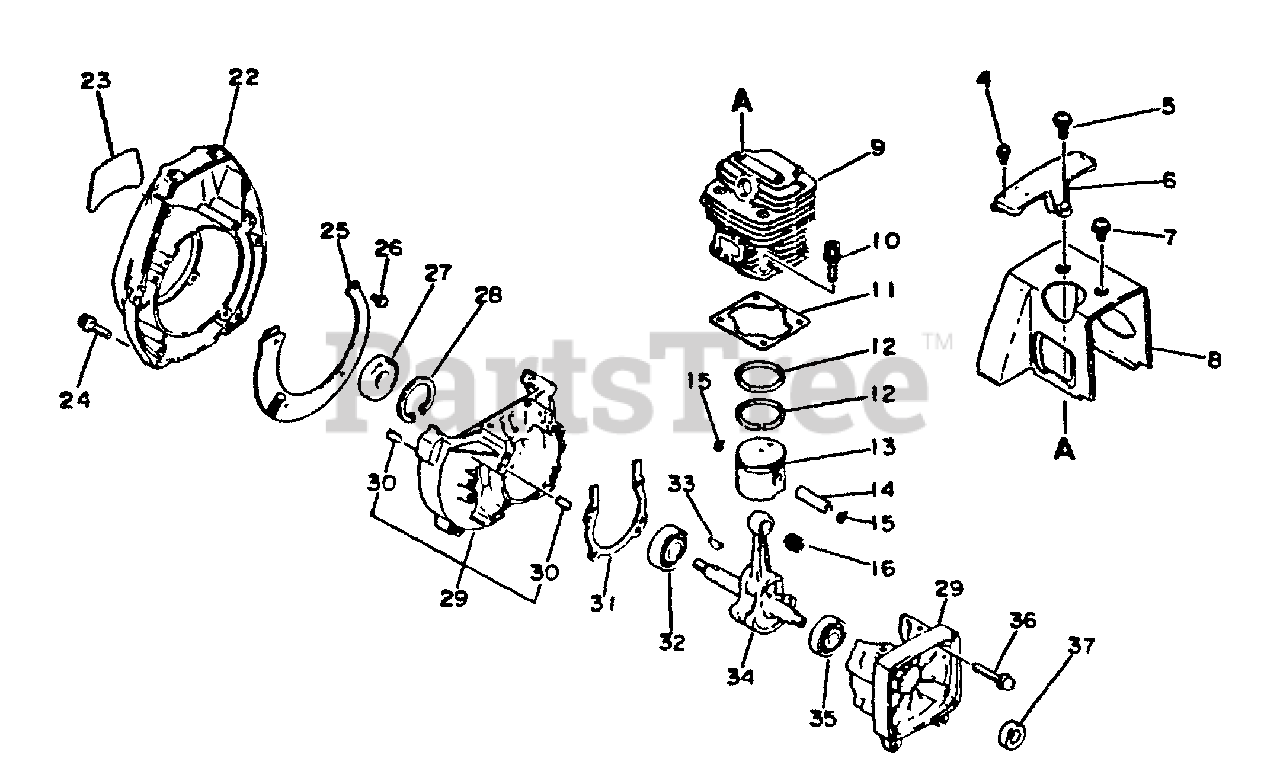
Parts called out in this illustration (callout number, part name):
4	SCREW - 4X14
5	SCREW - 5X16
6	GUARD - TOP
7	SCREW - 5X10
8	COVER, ENGINE
9	CYLINDER
10	SCREW - 5X20
11	GASKET, CYLINDER
12	RING, PISTON
13	PISTON
14	PIN, PISTON
15	RING, RETAINING
16	BEARING, NEEDLE
22	CASE, FAN
23	LABEL - MODEL
24	SCREW - 5X25
25	SHIELD, FAN
26	SCREW - 4X8
27	SEAL, OIL
28	RING, RETAINING - 35
29	CRANKCASE KIT
30	PIN - LOCATING
31	GASKET, CRANKCASE
32	BEARING, BALL - 6202
34	CRANKSHAFT ASSY
35	BEARING, BALL - 6201
36	SCREW - 5X30
37	SEAL, OIL
